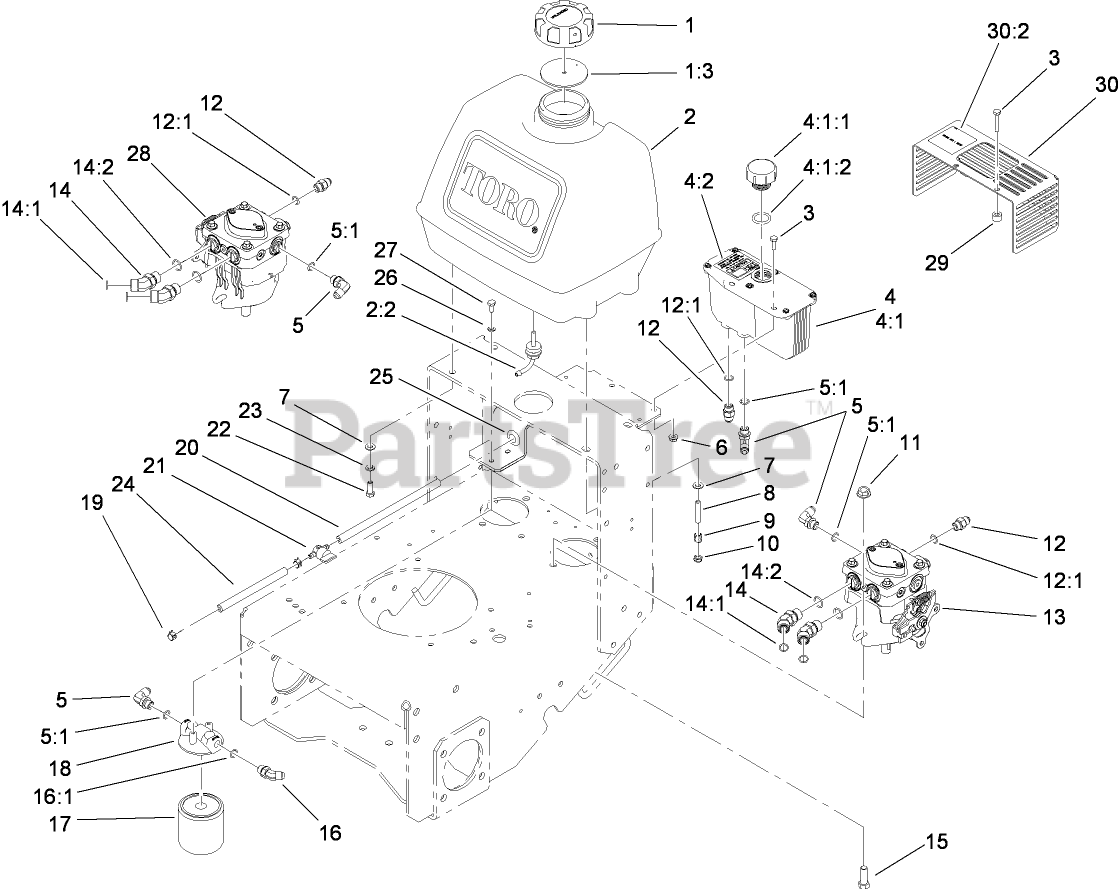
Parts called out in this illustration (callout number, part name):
1	GAS CAP ASM
1:3	GASKET-CAP, GAS
2	FUEL TANK ASM
2:2	FITTING-FUEL, BULKHEAD
3	SCREW-HH
4	HYD Reservoir ASM
4:1	Reservoir-HYD
4:1:1	CAP-RESERVOIR, HYD
4:1:2	GASKET-CAP
4:2	DECAL-TANK, HYD
5	FITTING-ELBOW, 90 DEG
5:1	O-RING
6	NUT-HF
7	WASHER-PLAIN
8	STUD-THREADED
9	SPRING-TANK, FUEL
10	NUT-LOCK, NI
11	NUT-HF
12	FITTING-STRAIGHT
12:1	O-RING
13	PUMP-HYD, LEFT
14	FITTING-HYD, 45 DEG
14:1	O-RING
14:2	O-RING
15	SCREW-HH
16	FITTING-ELBOW, 45 DEG
16:1	O-RING
17	FILTER-OIL, HYD (WINTER)
17	FILTER-OIL, HYD
18	HEAD-FILTER
19	CLAMP-HOSE
20	HOSE-FUEL
21	VALVE-FUEL
22	SCREW-HH
23	WASHER-LOCK
24	HOSE-FUEL
25	GROMMET
26	WASHER-LOCK
27	SCREW-HH
28	PUMP-HYD, RIGHT
29	Spacer
30	SHIELD ASM
30:2	DECAL-SURFACE, HOT (CE)
